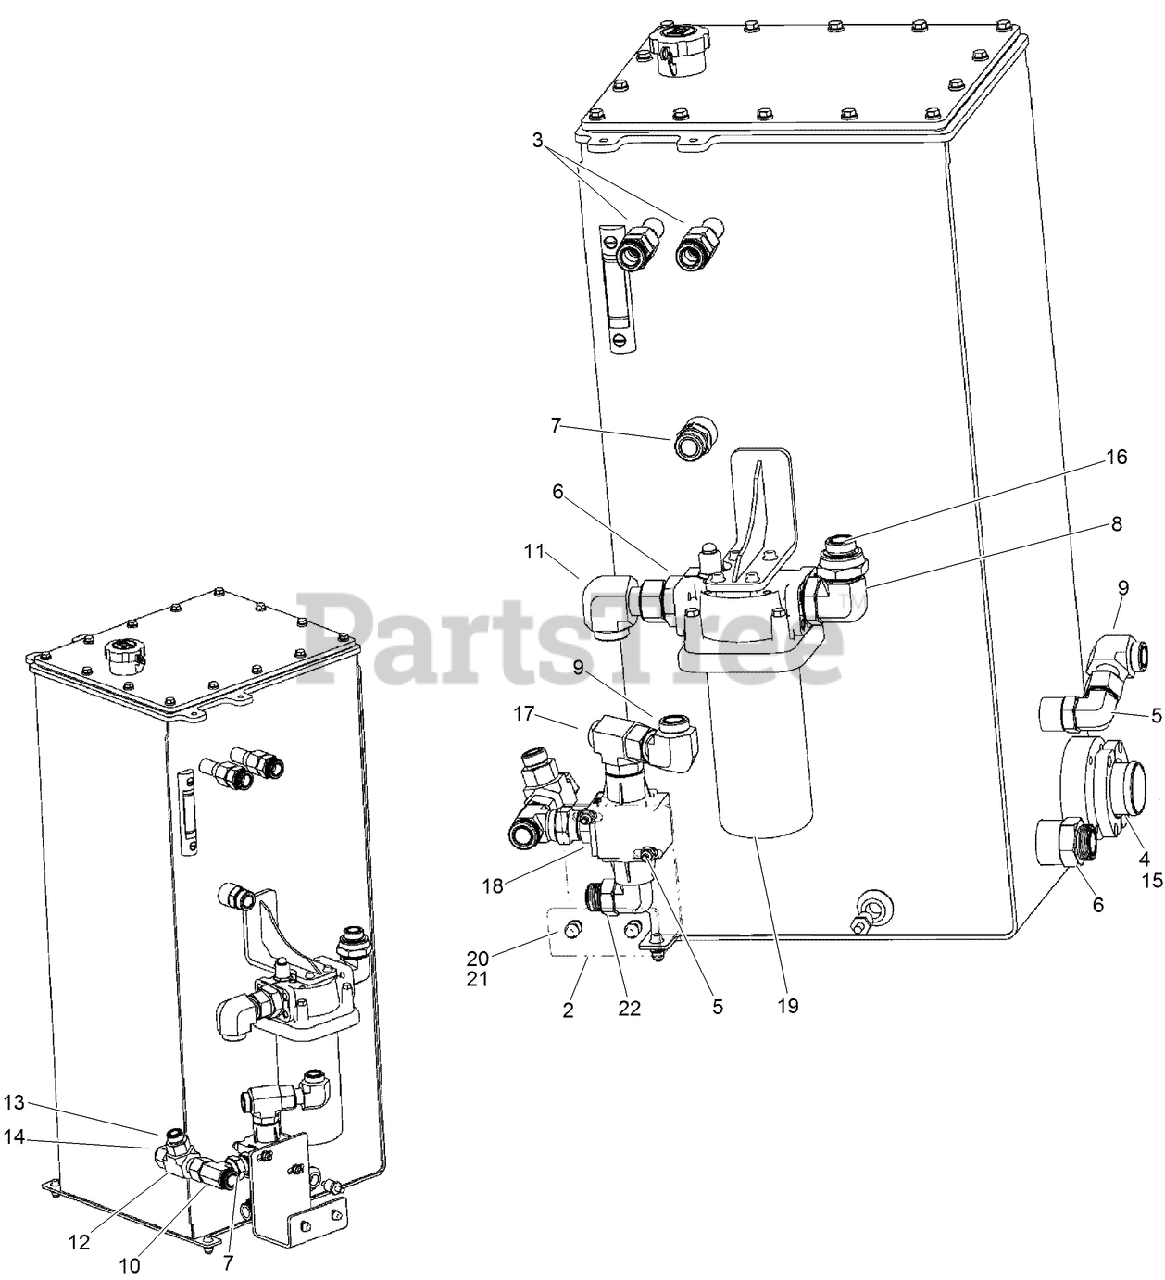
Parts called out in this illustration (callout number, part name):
2	PLATE - Mount, Thermal Bypass
3	FITTING-STRAIGHT
4	INSERT
5	CONNECTION - 90 Deg, -16 ORFS / -16 ORB
6	FITTING-STR
7	CONNECTION - Straight, -16 ORFS / -16 ORB
8	FITTING-ELBOW 90
9	CONNECTION - 90 Degree, -16 ORFS / -16 ORFS
10	FITTING-TEE
11	FITTING-ELBOW, 90
12	FITTING-TEE
13	FITTING-REDUCER
14	FITTING-REDUCER
15	SPLIT FLANGE KIT
16	FITTING-REDUCER
17	CONNECTION - Branch Tee, -16 ORFS / -16 ORB
18	VALVE-THERMOSTAT
19	FILTER-HYD, RETURN
20	SCREW-HH
21	NUT-TORQUE, PREVAILING
22	SCREW-FLANGE
